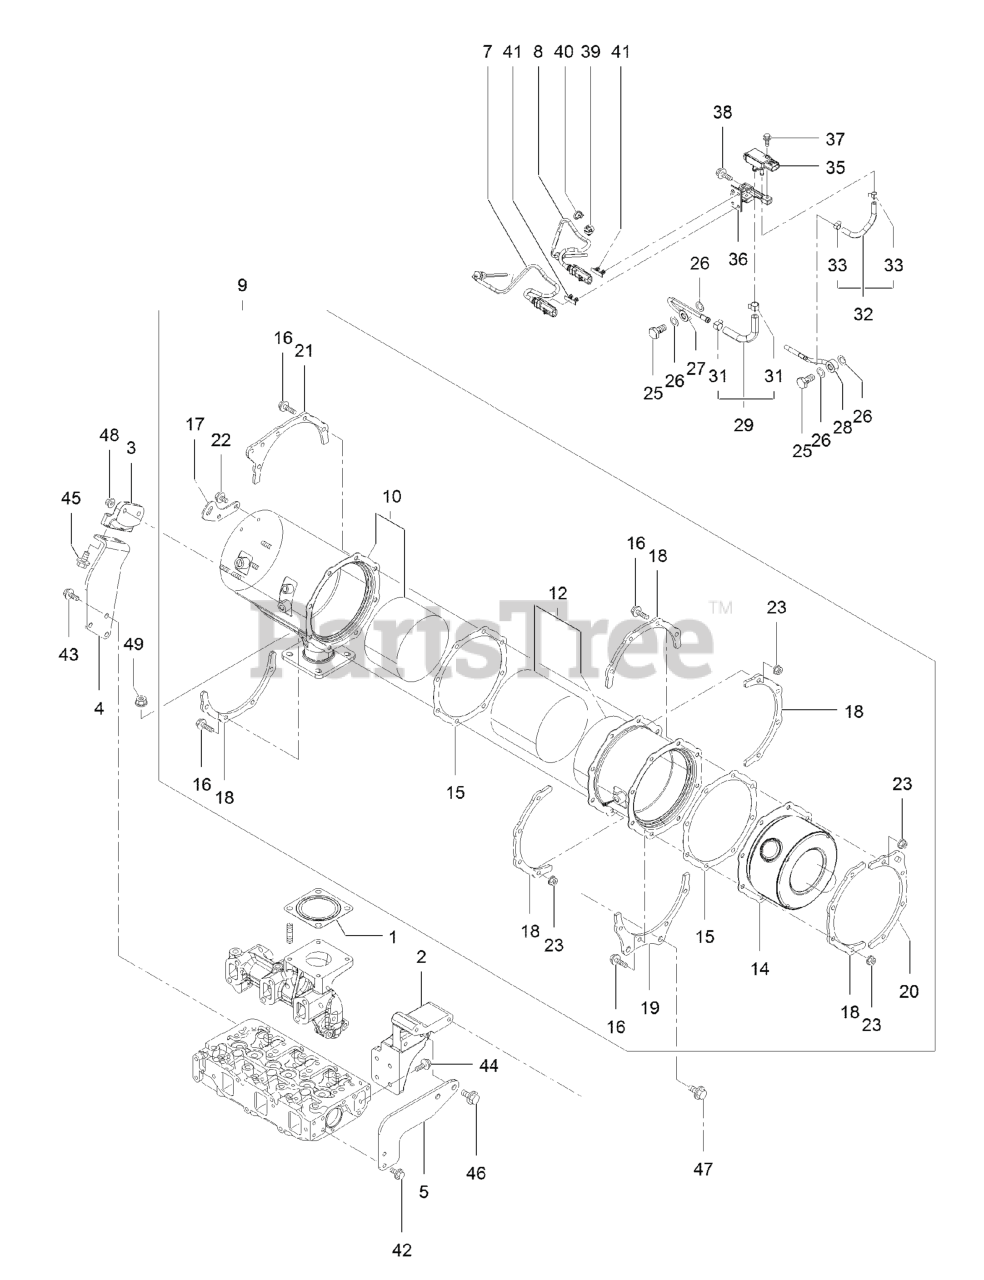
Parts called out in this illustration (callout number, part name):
1	GASKET-SILENCER
2	STAY-D P F
3	STAY-D P F
4	STAY-D P F
5	STAY-D P F
7	SENSOR-TEMP, EXHAUST
8	SENSOR-TEMP, EXHAUST
9	D P F ASM
10	CASE-D O C
12	CASE-FILTER, SOOT
14	SILENCER-D P F
15	GASKET-D P F
17	LIFTER-D P F
18	STIFFENER-D P F, A
19	STIFFENER-D P F, B
20	STIFFENER-D P F, C
21	STIFFENER-D P F, C
25	BOLT-JOINT, PIPE
26	GASKET-SENSOR
27	SENSOR PIPE ASM
28	SENSOR PIPE ASM
29	EXHAUST HOSE ASM
31	Clip-Hose
32	EXHAUST HOSE ASM
33	Clip-Hose
35	SENSOR-PRESSURE
36	BRACKET-SENSOR
39	BAND-CLIP
41	CLIP-CONNNECTOR
42	BOLT
43	BOLT
